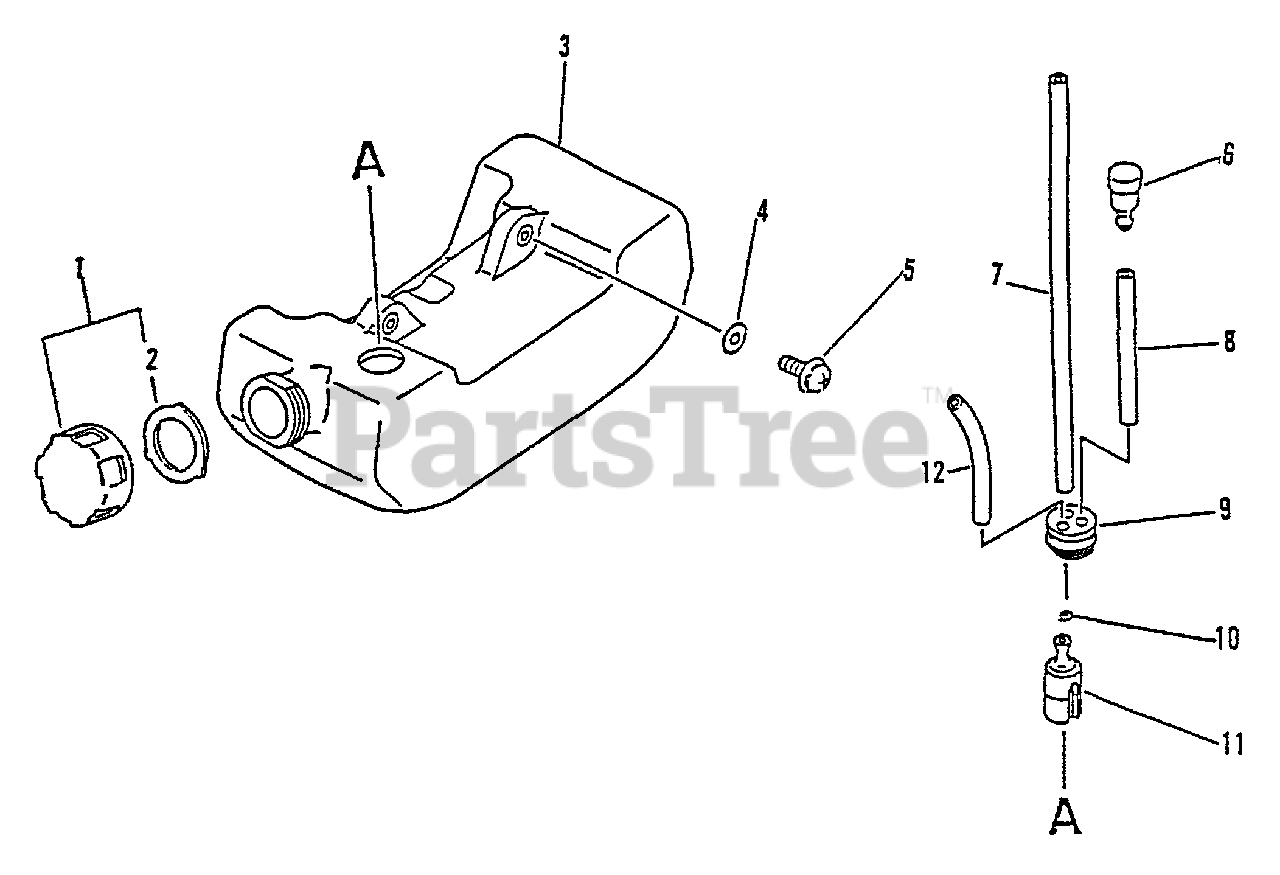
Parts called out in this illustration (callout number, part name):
1	CAP ASSY
2	GASKET, FUEL CAP
3	TANK, FUEL
4	WASHER 5.5×12×0.8
5	SCREW 5×16
6	VENT ASSY
7	PIPE, FUEL 3x-5x-180
8	PIPE, FUEL 3x-5x-70 BLACK
9	GROMMET, FUEL
10	CLIP 6 MM
11	FILTER, FUEL
12	PIPE, FUEL 3×6×80 CLEAR
